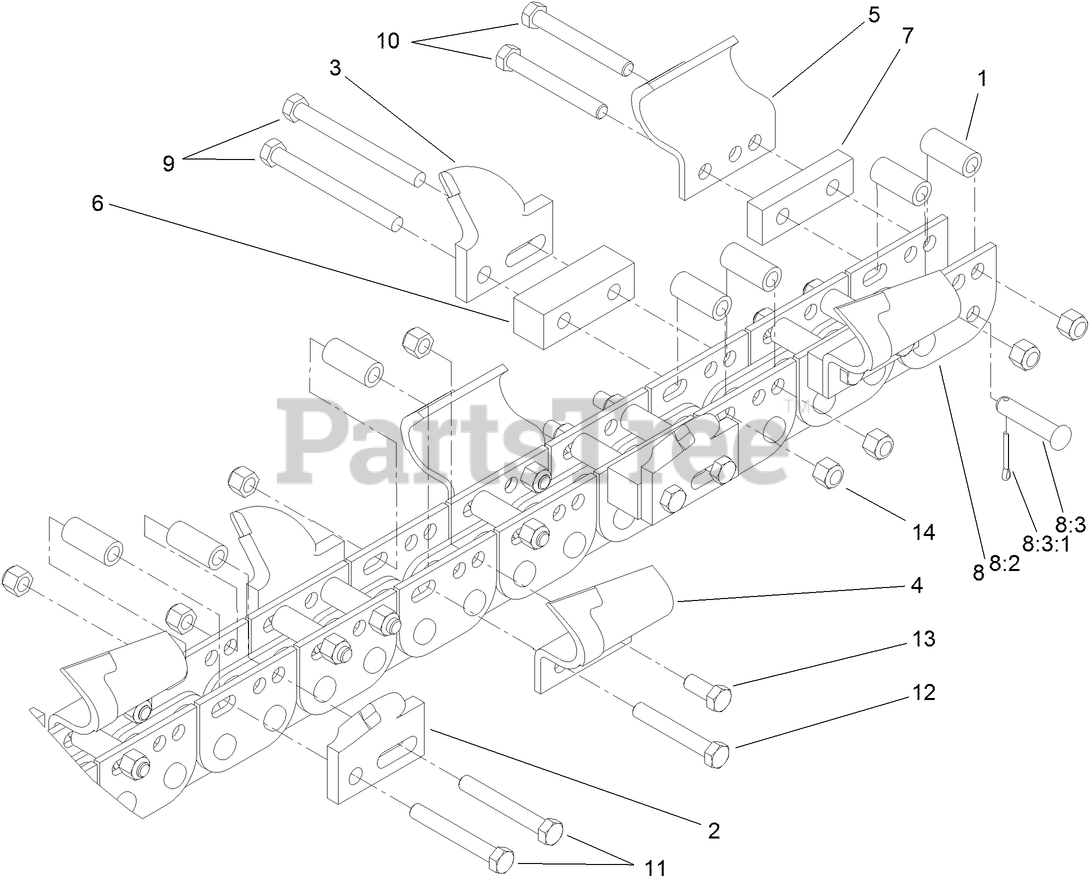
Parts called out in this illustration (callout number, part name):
1	SPACER-TUBE
2	TOOTH- ROCK, LH
3	TOOTH-ROCK, RH
4	TOOTH-SOIL, LH
5	TOOTH-SOIL, RH
6	SPACER-CUT, 6 INCH
7	SPACER-CUT, 5 INCH
8	CHAIN-BARE, 24 STATION
8:2	LINK REPAIR KIT
8:3	PIN-CONNECTING (61MM)
8:3:1	PIN-COTTER
9	SCREW-HH
10	SCREW-HH
11	SCREW-HH
12	SCREW-HH
14	NUT-HEX
